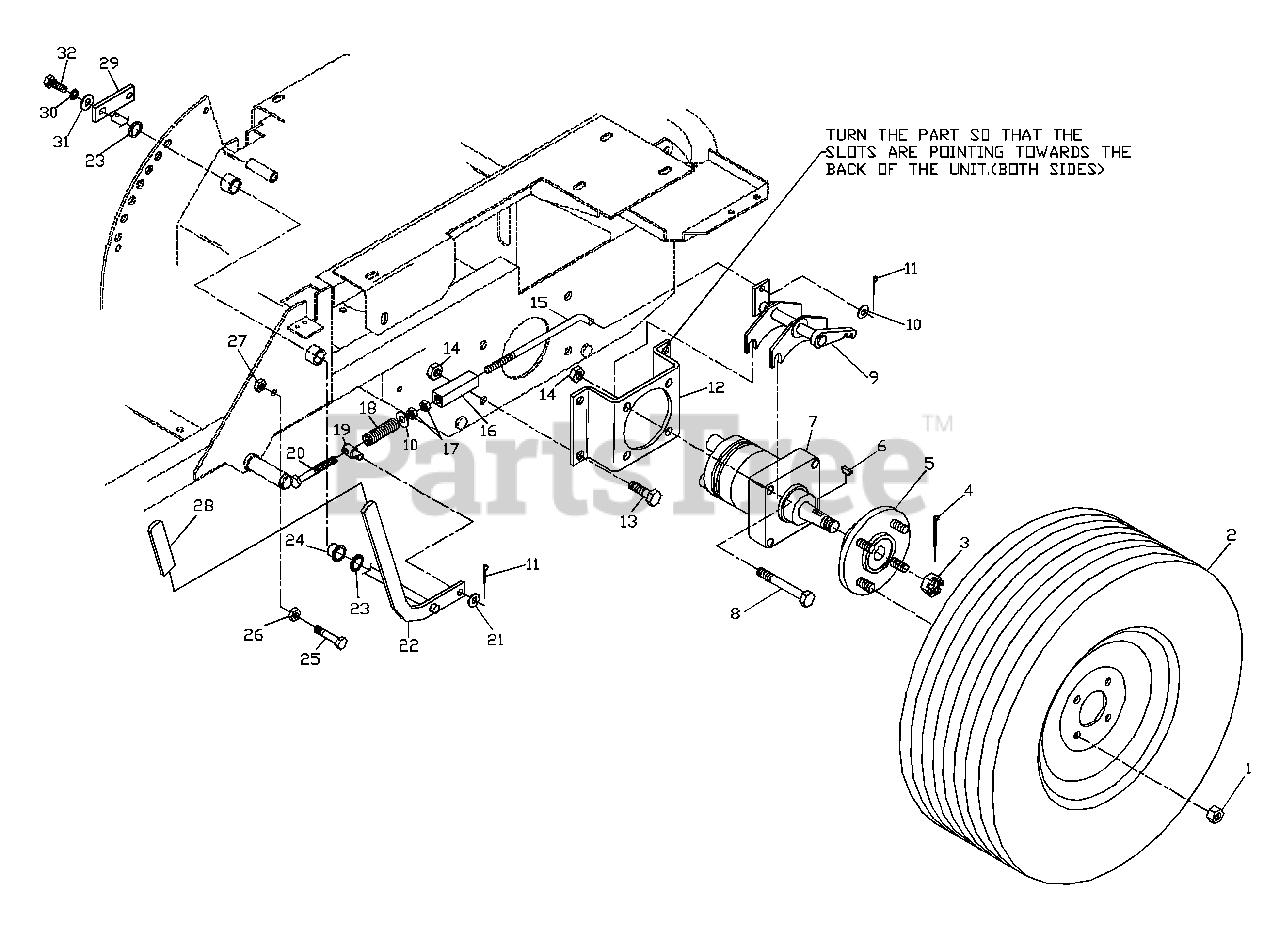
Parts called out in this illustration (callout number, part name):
1	LUG NUT 1/2F
2	REAR TIRE ASM.
2	RIM
2	VALVE STEM
3	HEX SLOTTED NUT
4	COTTER PIN
5	HUB, W/SPROCKET
6	KEY, #808 WOODRUFF
7	WHEEL MOTOR
8	HCS 1/2C X 2 3/4
9	BRAKE WELDMENT LEFT
10	WASHER 5/16 FLAT
11	1/8 X 3/4 COTTER PIN
12	MOTOR STANDOFF
13	HCS 1/2C X 1 1/4 SERRATED HEAD
14	NUT 1/2C NYLOC
15	BRAKE LINKAGE
16	TURNBUCKLE
17	5/16C HEX NUT
19	BRAKE SWIVEL
20	HCS 5/16C, SPECIAL
21	3/8 SAE WASHER
22	PIVOT SHAFT
23	1/2" MACHINERY BUSHING
25	HCS 3/8C X 1 3/4
26	3/8C WHIZ NUT
27	NUT 3/8C CENTERLOCK
29	ARM, PARK BRAKE
30	1/4" LOCKWASHER
31	WASHER 1/4" FLAT
32	HCS 1/4C X 5/8"
